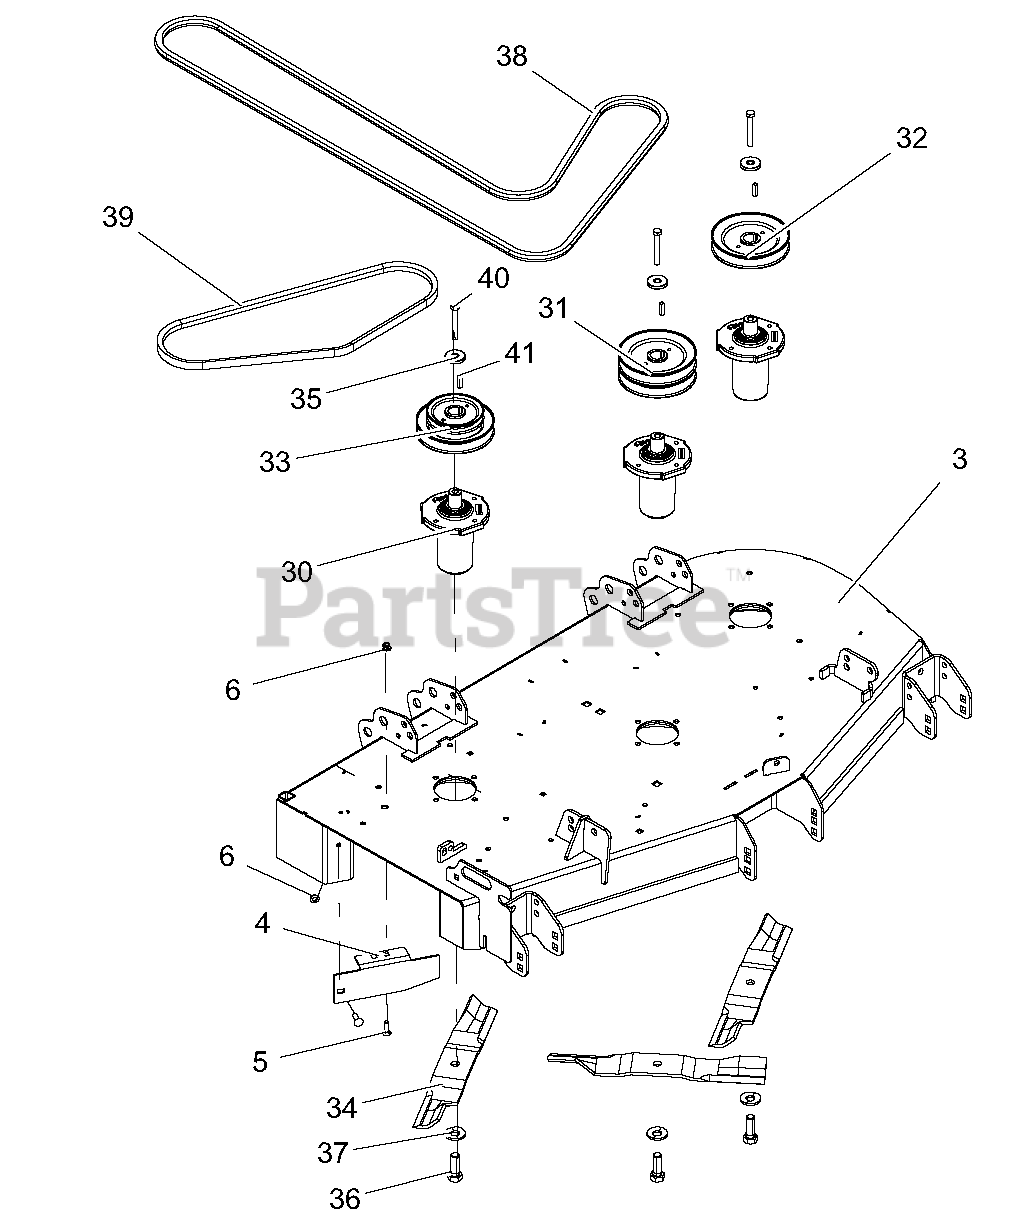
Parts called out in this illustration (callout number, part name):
3	WLDMT, 48’’ SIDE DISCH DECK-RED
4	BAFFLE, DISCHARGE, 44"-48"-RED
5	@BLT-RDHDSQSHNK .31-18X1.00 G5 Y
6	NUT-LK-NYL-FLG .31-18 YWZC
30	ASM, SPINDLE - DUCTILE
31	PULLEY, DOUBLE-1" ID X 5.75" OD-BLACK
32	PULLEY, V - 1" ID X 5.75" OD-BLACK
33	PULLEY, DBL-1"IDX5.75"&3.50"OD (SN 020000 - 020999)
33	PULLEY, DOUBLE -1" ID X 5.75" & 4.25" OD (SN 021000 and up)
34	BLADE, 16.19" MOWER (HI-LIFT)
35	RETAINER, SHEAVE SPINDLE
36	BLT, HEX .62-18X1.75 GR8 YWZC
37	WSHR, BLVL .63X1.625X.14
38	BELT, BB 118.00 WRAPPED HEX
39	V-Belt, B-Raw Edge Cogged
40	BLT-HEX .38-16X2.75 GR8 YWZC
41	KEY-SQ .250X.250X1.00
